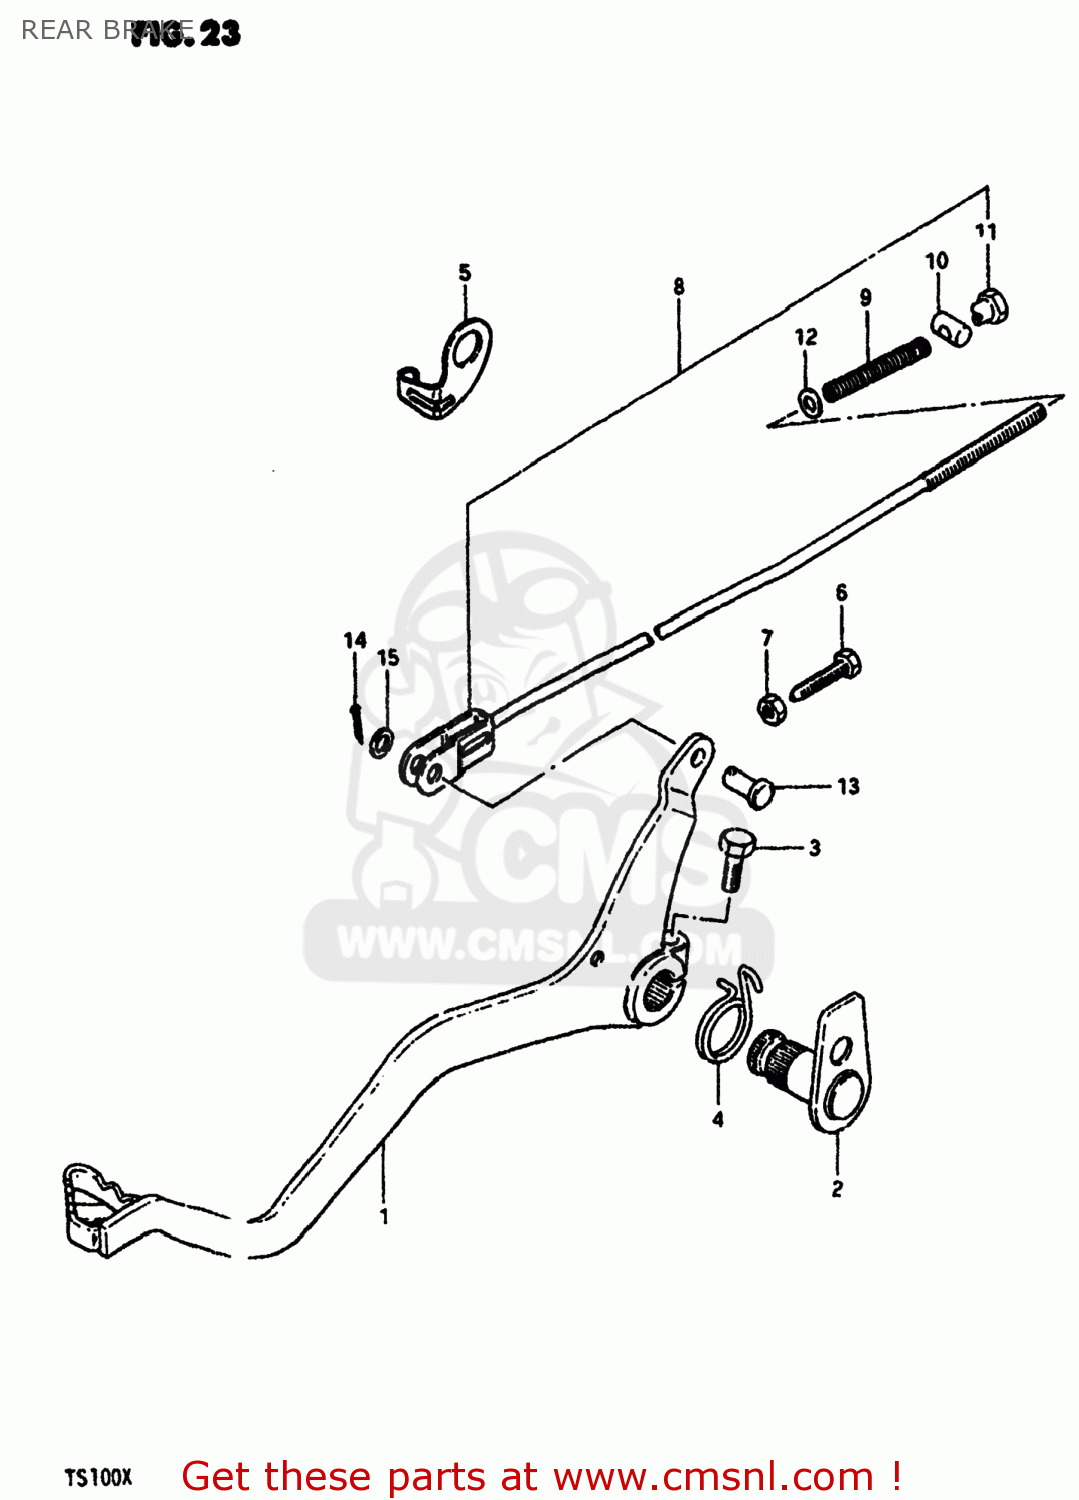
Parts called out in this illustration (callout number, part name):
1	PEDAL,BRAKE
2	ARM,BRAKE PEDAL
3	BOLT
4	SPRING
5	HOOK,STOP LAMP SWITCH SPRING
6	BOLT(6X23)
7	NUT
8	ROD ASSY,RR BRAKE
9	SPRING
10	PIN
11	NUT
12	WASHER
13	PIN(L:13.5)
14	PIN 20X20
15	WASHER
